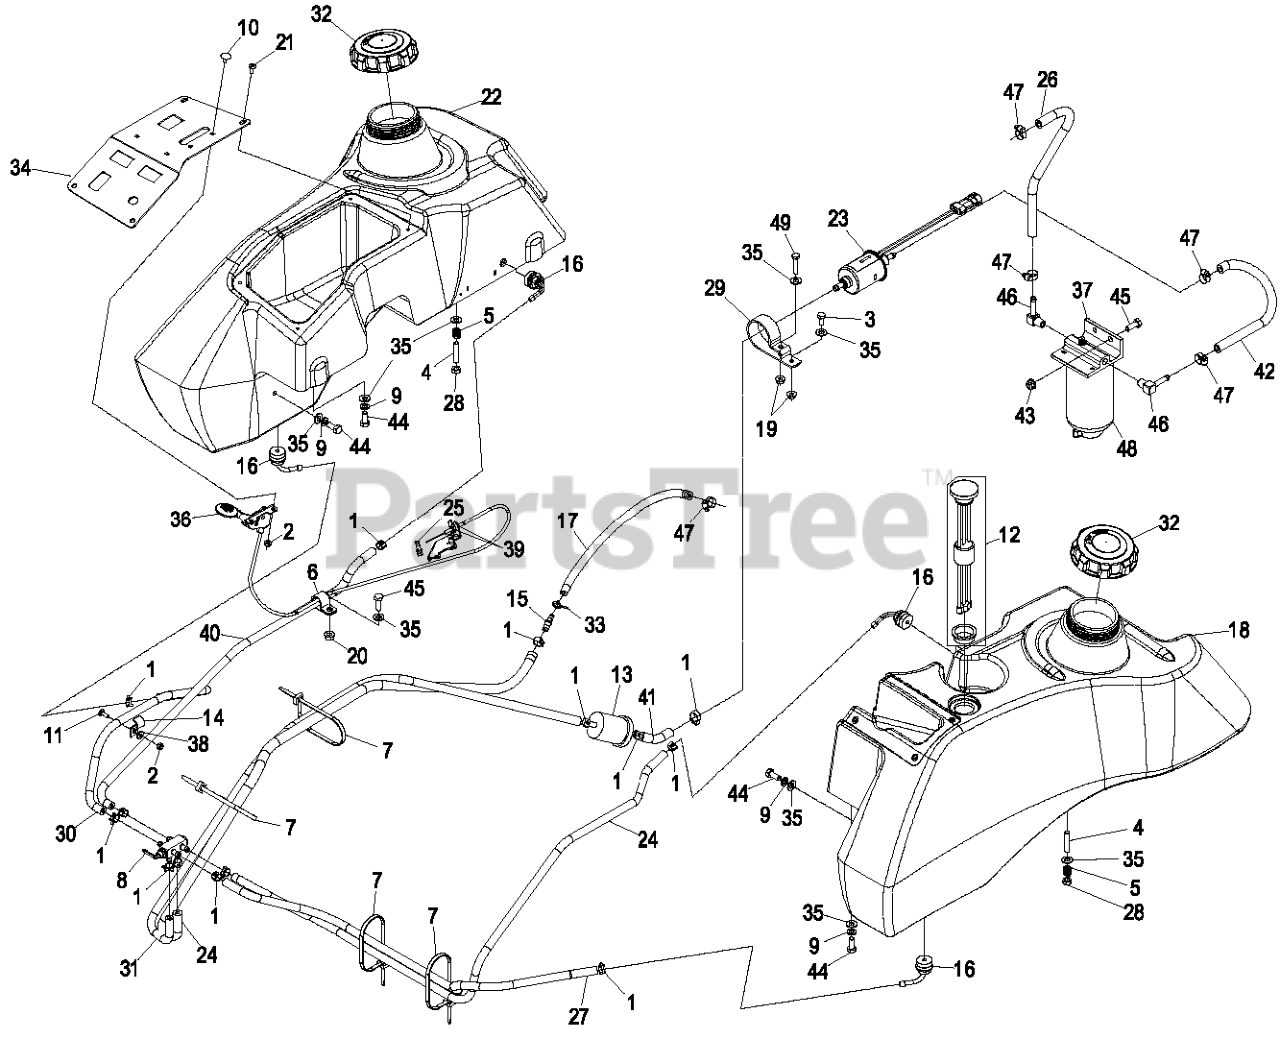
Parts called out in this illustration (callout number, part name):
1	CLAMP-HOSE
2	NUT-LOCK, NI
3	SCREW-HH
4	STUD
5	SPRING-TANK, FUEL
6	CLIP-LOOM
7	TIE-PLASTIC
8	VALVE,FUEL SELECTOR 5/16
9	WASHER-LOCK
10	BOLT-CARR
11	BOLT-CARR
12	KIT, CT FUEL GAGE REPL.
13	FILTER-INLINE
14	CLIP-HALF, LOOM
15	CONNECTOR
16	FITTING,FUEL BULKHEAD W/O
17	HOSE-FUEL
18	ASM,FUEL TANK LXS LH
21	SCREW-PPH
22	ASM, FUEL TANK LXS RH
23	PUMP-FUEL
24	HOSE-FUEL
25	SWIVEL-STOP, CABLE
26	HOSE-FUEL
27	HOSE-FUEL
28	NUT-LOCK, NI
29	BRACKET-PUMP, FUEL
30	HOSE-FUEL
31	HOSE-FUEL
32	CAP-BIODIESEL
34	ASM, CONTROL PANEL W/DECA
35	WASHER-PLAIN
36	CABLE,THROTTLE
37	FUEL FILTER ASM
38	WASHER-FLAT
39	NUT-JAM
40	HOSE-FUEL
41	HOSE-FUEL
42	HOSE-FUEL
43	NUT-HF, NI
44	SCREW-HH
45	SCREW-HH
46	FITTING-HYD, 90 DEG
47	CLAMP-WORM
48	FILTER-FUEL
49	SCREW-HH
